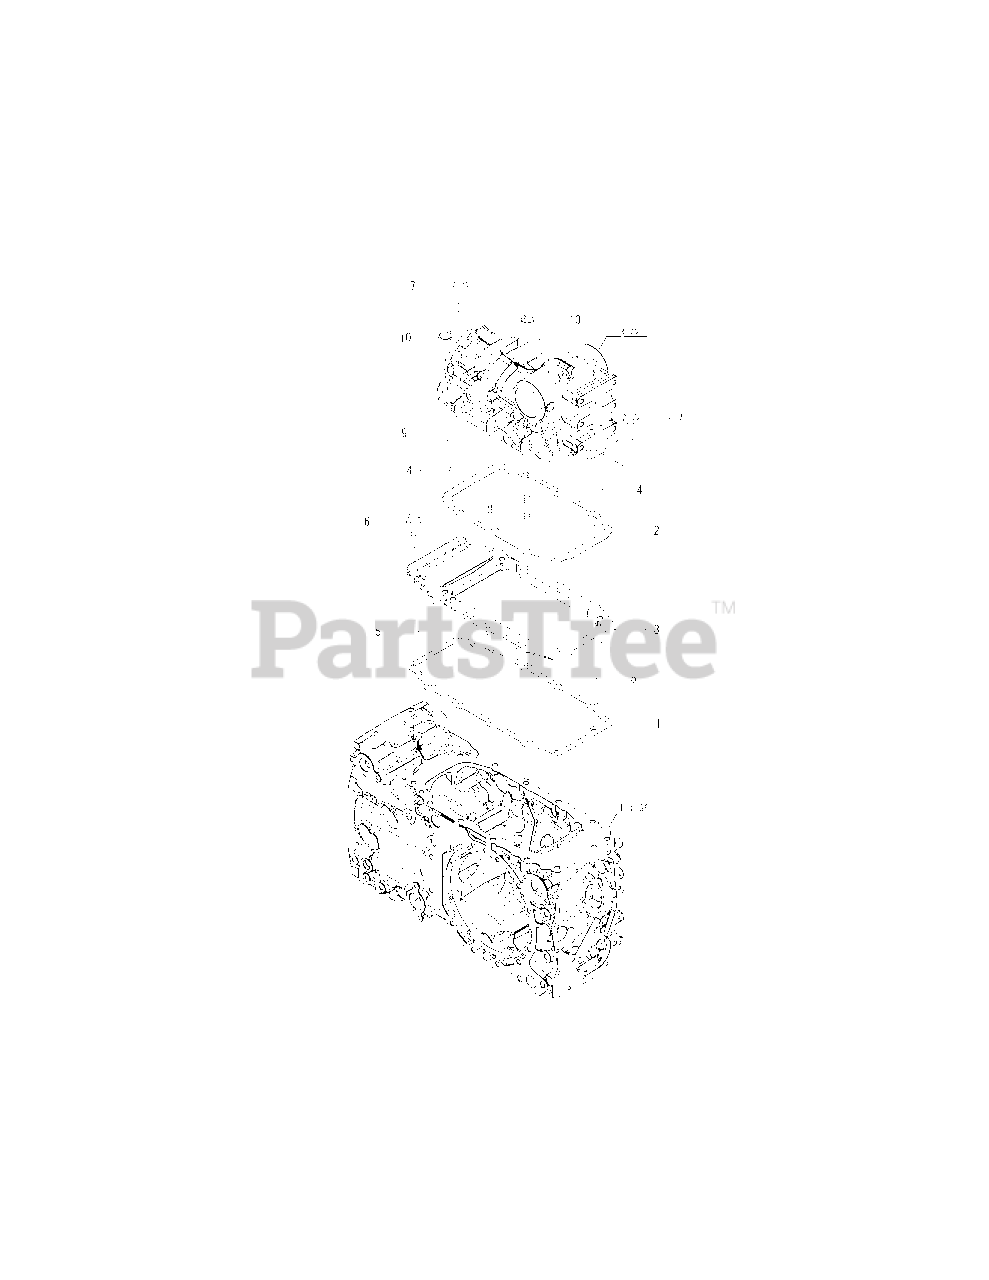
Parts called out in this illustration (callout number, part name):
1	PACKING, HOUSING
2	GASKET,HOUSING
4	PARALLEL PIN 10X 18
5	PARALLEL PIN 10X 18
6	BOLT, M12X 40 PLATED
8	STUD M12X 70 PLATED
9	STUD,BOLT 12 X 50
